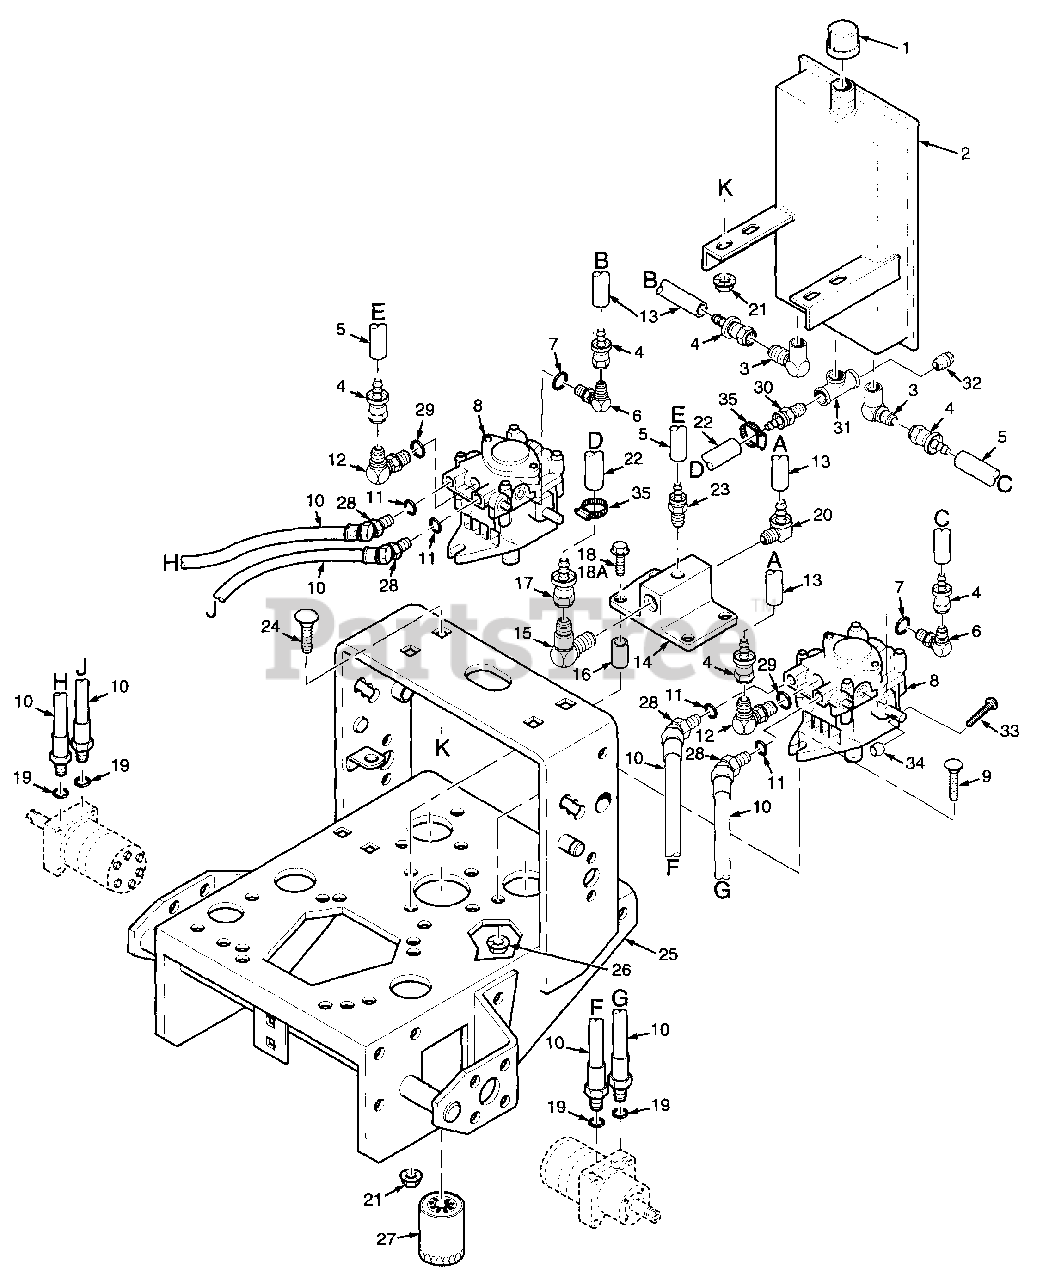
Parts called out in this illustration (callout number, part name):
1	Cap, Oil Reservoir
2	Oil Reservoir
3	Elbow, 90 deg. Female 1/4 NPT to 1/4 JIC Male
4	Coupling, 7/16-20 SAE Flare Swivel to 1/4" Hose Push On
5	Hose, 1/4" ID - 12" Long
6	Elbow, 90 deg 7/16-20 JIC to 9/16-18 "O" Ring
7	O-Ring
8	Pump, Sunstrand BDP-10L117
9	Bolt, Carriage, 3/8-16 x 1-1/4
10	Hose, Pump to Motor
11	O-Ring
12	Elbow, 90 deg., 7/16-20 JIC x 7/16-20 O-Ring
13	Hose, 1/4" ID - 10" Long
14	Oil Filter Base
15	Elbow, 90 deg Male 3/4-16 JIC to 1/2" Male NPT
16	Spacer, Oil Filter Base
17	Coupling, 3/4-16 SAE to 1/2" Hose Push On
18	Capscrew, 5/16-18 x .75" (For 16") Serr. Flange
18A	Capscrew, 5/16-18 x 2.25" Serr. Flange
19	O-Ring
20	Elbow, 90 deg. Male 1/4 NPT to 1/4 Hose Push On
21	Nut, 5/16-18 Serr Flange
22	Hose, Formed 1/2" ID
23	Coupling, 1/4 straight Male NPT to 1/4 Hose Push On
24	Bolt, 5/16-18 x 3/4" Carriage
25	Engine Deck (20" Wide) W/Decals
26	Nut, 3/8-16 Serr Flange
27	Oil Filter
28	Elbow, 45 Deg -3/4-16 JIC Male x Male 3/4-16 O-Ring
29	O-Ring
30	Coupling, 3/8 Pipe to 1/2 Push-on
31	T-Fitting, 3/8 NPT
32	Plug, 3/8-18 NPTF Magnetic
33	Screw, 1/4-20 x 2.0" Round Head Phillips
34	Nut, 1/4-20 Elastic Stop
35	Clamp, 87 max dia
